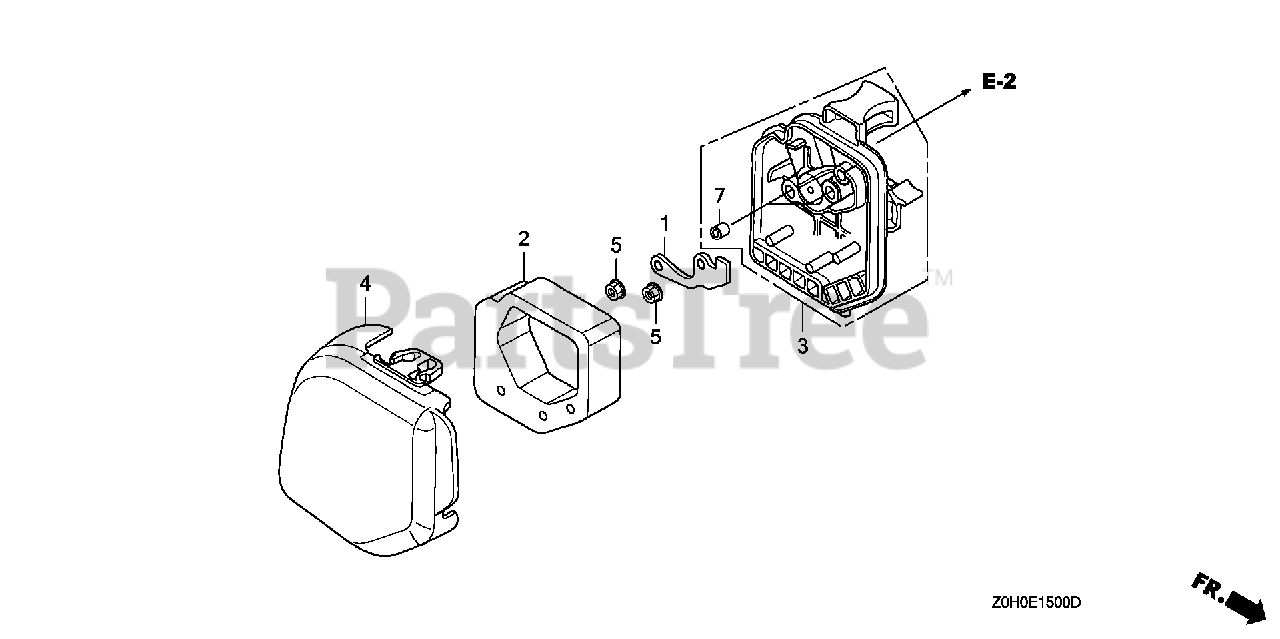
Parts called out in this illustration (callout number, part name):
1	PLATE, OIL TRAP
2	ELEMENT, AIR CLEANER
3	HOUSING, AIR CLEANER
4	COVER, AIR CLEANER
5	NUT, FLANGE (5MM)
7	COLLAR, AIR CLEANER
